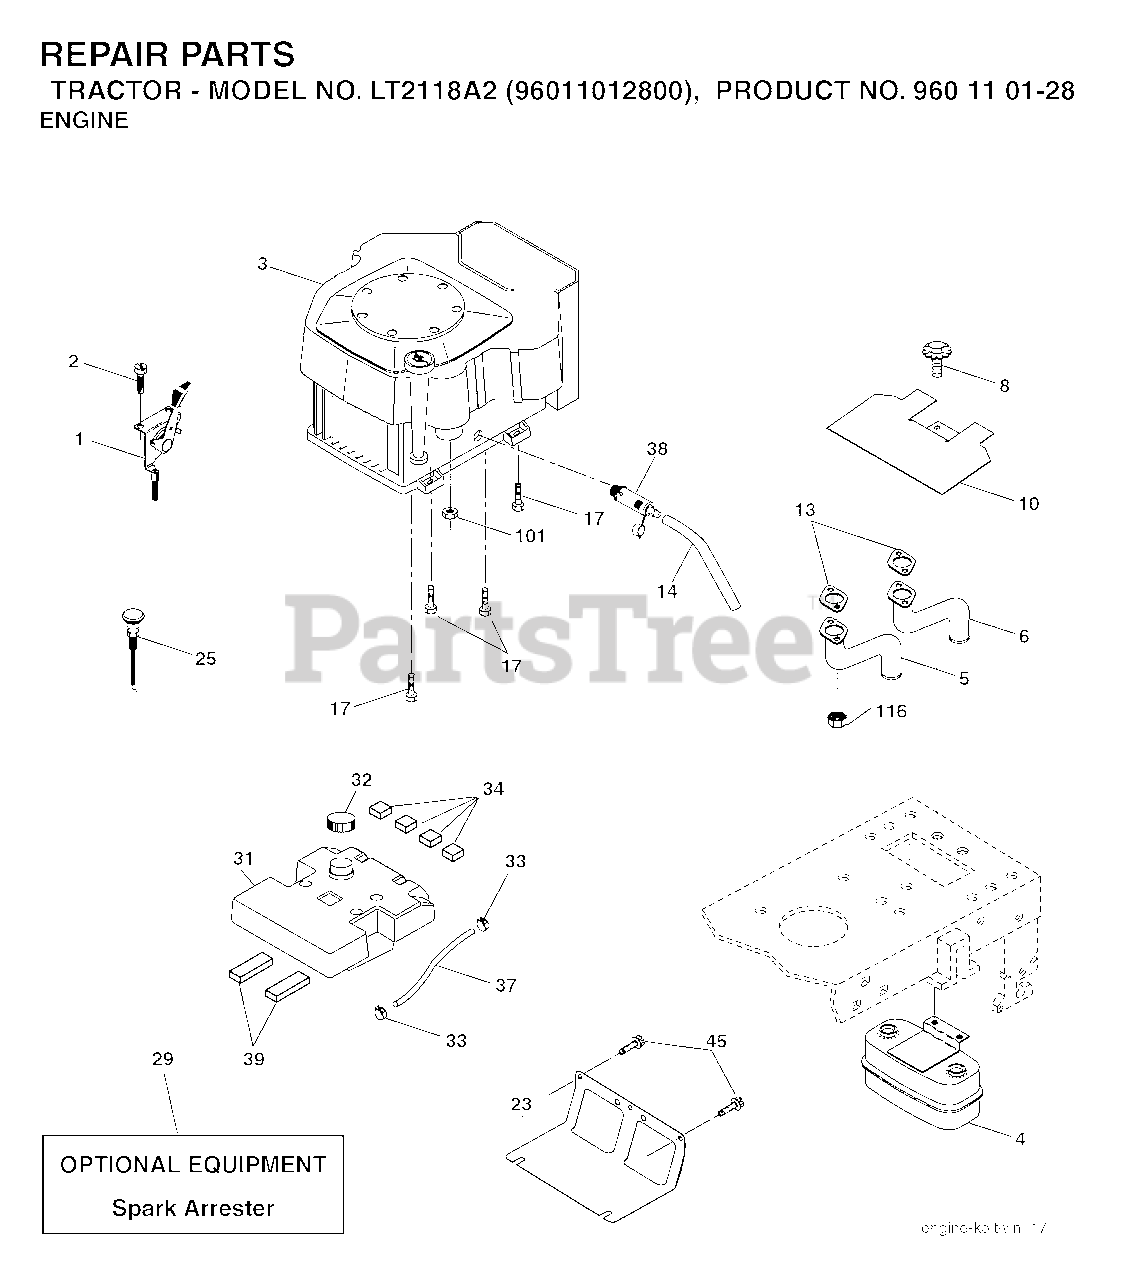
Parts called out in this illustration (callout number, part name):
1	CONTROL.THROTTLE.KAWA
2	SCREW
4	MUFFLER.TWIN.CYL.LOW.TONE
5	PIPE-EXHAUST LH
6	PIPE-EXHAUST RH
8	BOLT, 5/16-18 X 1 3/4
10	RP SHIELD HEAT MUFFLER
14	TUBE, DRAIN OIL ASM.
23	SHEILD.BROWNING.DBR.GUARD
25	CONTROL, CHOKE
29	ARRESTER SPARK (OPTIONAL)
31	TANK.FUEL(3.5.GAL)
32	FUEL CAP
33	HOSE CLAMP
34	PAD-SPACER LT
38	PLUG DRAIN OIL EASY
39	PAD IDLER TI
45	SCREW, 3/8-16X3/4
101	FLANGE NUT
